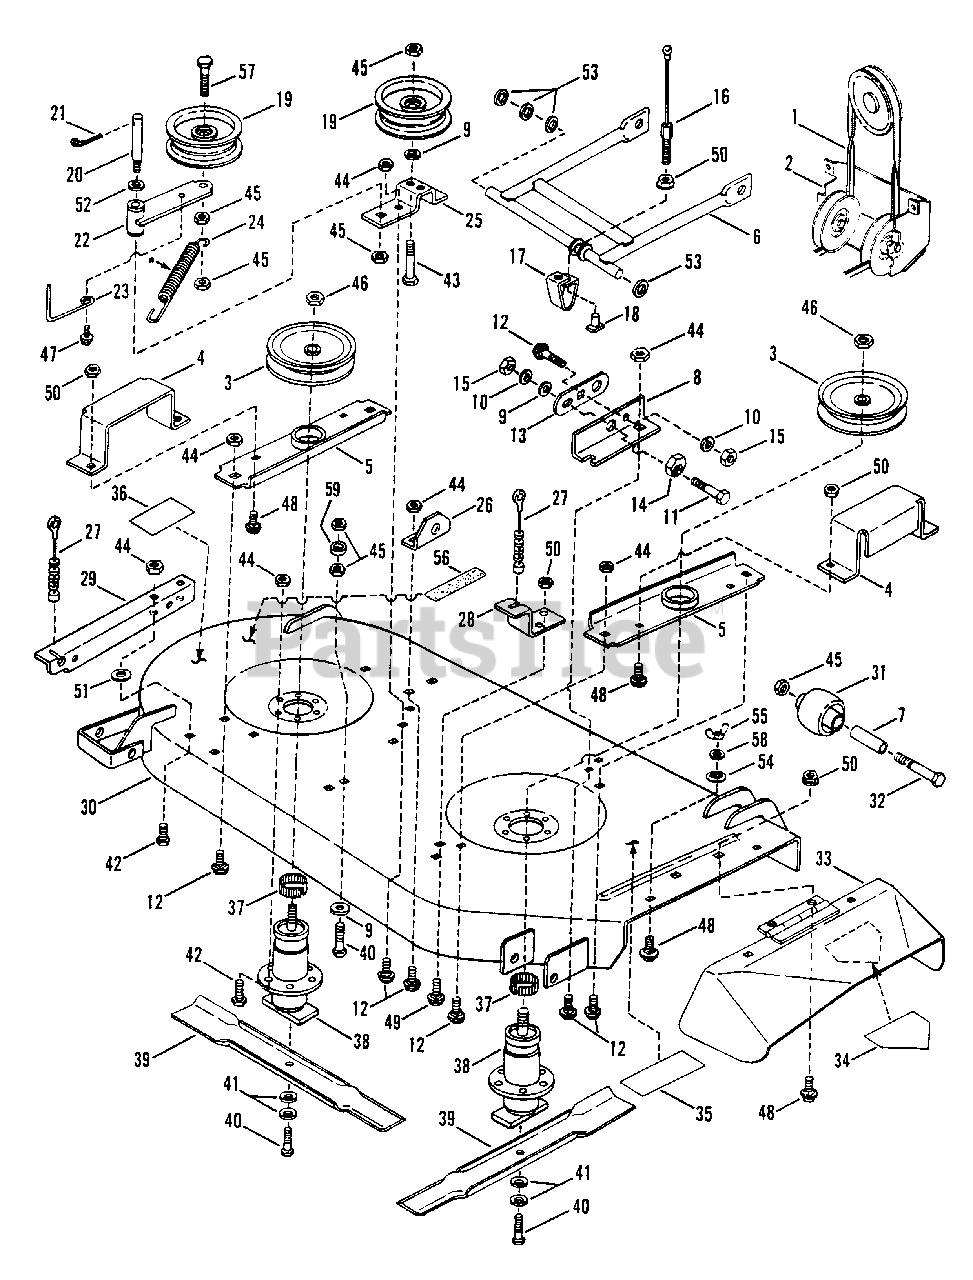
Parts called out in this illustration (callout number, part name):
1	BELT, 42" Deck Drive
2	ASSEMBLY, Mule Drive
3	PULLEY, 5 3/4" O.D.
4	GUARD, Pulley
5	BRACE, Spindle
6	ASSEMBLY, Front Lift Arm
7	SPACER, Wheel
8	BRACKET, Right Front
9	WASHER, 3/8 SAE
10	WASHER, 3/8 Split Lock
11	SCREW, 3/8-16 x 1" Hex Head Cap, Grade 5
12	BOLT, 3/8-16 x 3/4" Carriage, Grade 2
13	LINK, Adjustment
14	RING, Adjustment
15	NUT, 3/8-16 Hex
16	CABLE, Front Lift
17	BRACKET, Front Lift Arm Hanger
18	T-NUT, 5/16-18
19	PULLEY, 4.1" O.D.
20	STUD, 3/8-24 Idler
21	COTTER-PIN, 1/8 x 1"
22	ASSEMBLY, Idler Arm
23	GUIDE, Belt
24	SPRING, Idler Arm
25	BRACKET, Idler
26	BRACKET, Left Front
27	CABLE, Rear Lift
28	BRACKET, Rear Lift, Right Side
29	BRACKET, Rear Lift, Left Side
30	DECK, 42" Cutter
31	WHEEL, Gage
32	SCREW, 3/8-24 x 3-3/4" Hex Head Cap, Gr.5
33	DEFLECTOR
34	DECAL, DANGER
35	DECAL, CAUTION, Deflector in Place
36	DECAL, CAUTION, Rotating Blades
37	RING, Tolerance, 3/4"
38	ASSEMBLY, Spindle
39	BLADE, 21"
40	SCREW, 3/8-24 x 1-1/4" Hex Head Cap, Grade 5
41	WASHER, Cone
42	BOLT, 3/8-16 x 3/4" Hex Flange Lock
43	SCREW, 3/8-24 x 1-3/4" Hex Head Cap, Grade 5
44	NUT, 3/8-16 Hex Flange Lock
45	NUT, 3/8-24 Hex Lock
46	JAM-NUT, 3/4-16 Hex Center Lock
47	SCREW, 1/4-20 x 5/8" Self-Tapping, Grade 5
48	BOLT, 5/16-18 x 5/8" Carriage, Grade 5
49	BOLT, 5/16-18 x 3/4" Carriage, Grade 5
50	NUT, 5/16-18 Hex Flange Lock, Grade 5
51	WASHER, 3/8" Flat
52	WASHER, 5/8 SAE
53	WASHER, Spacer
54	RETAINER, 5/16 Bolt
55	WING-NUT, 5/16-18
56	FOOTPAD
57	SCREW, 3/8-24 x 2" Hex Head Cap, Grade 5
58	WASHER, 5/16 Split Lock
59	SPACER
